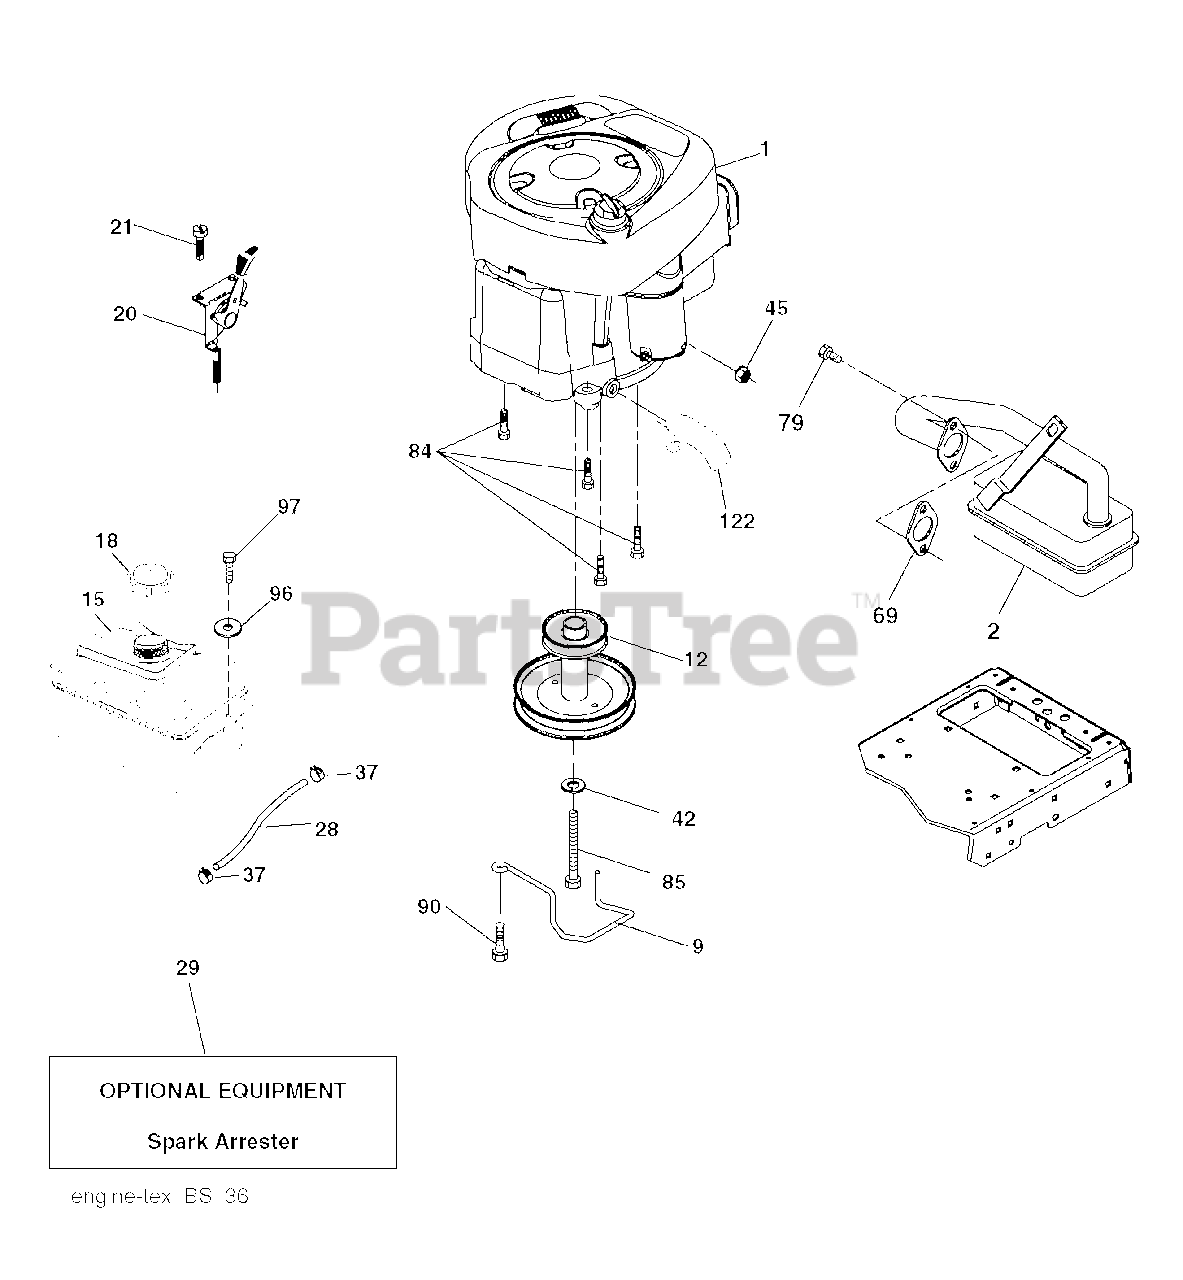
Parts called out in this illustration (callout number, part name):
9	KEEPER.BELT.ENGINE.3.25
12	PULLEY ENGINE
15	TANK FUEL FRT 1.5 GAL
18	CAP ASM.FUEL.2.25"FR.
20	CONTROL.THCK.COBRA.BS
21	SCREW.#10 X 0.750.BOS THREAD
29	ARRESTER SPARK (OPTIONAL)
42	LOCKWASHER
45	NUT
69	REPL BY 532 27 22-93
79	SCREW.SOCKET HD.5/16-1
85	BOLT HEX 7/16-20X4-1/4"
90	SCREW 3/8-16X1
97	SCREW HEXWSHR 1/4-20X3/4
122	EXTENSION DRAIN OIL
